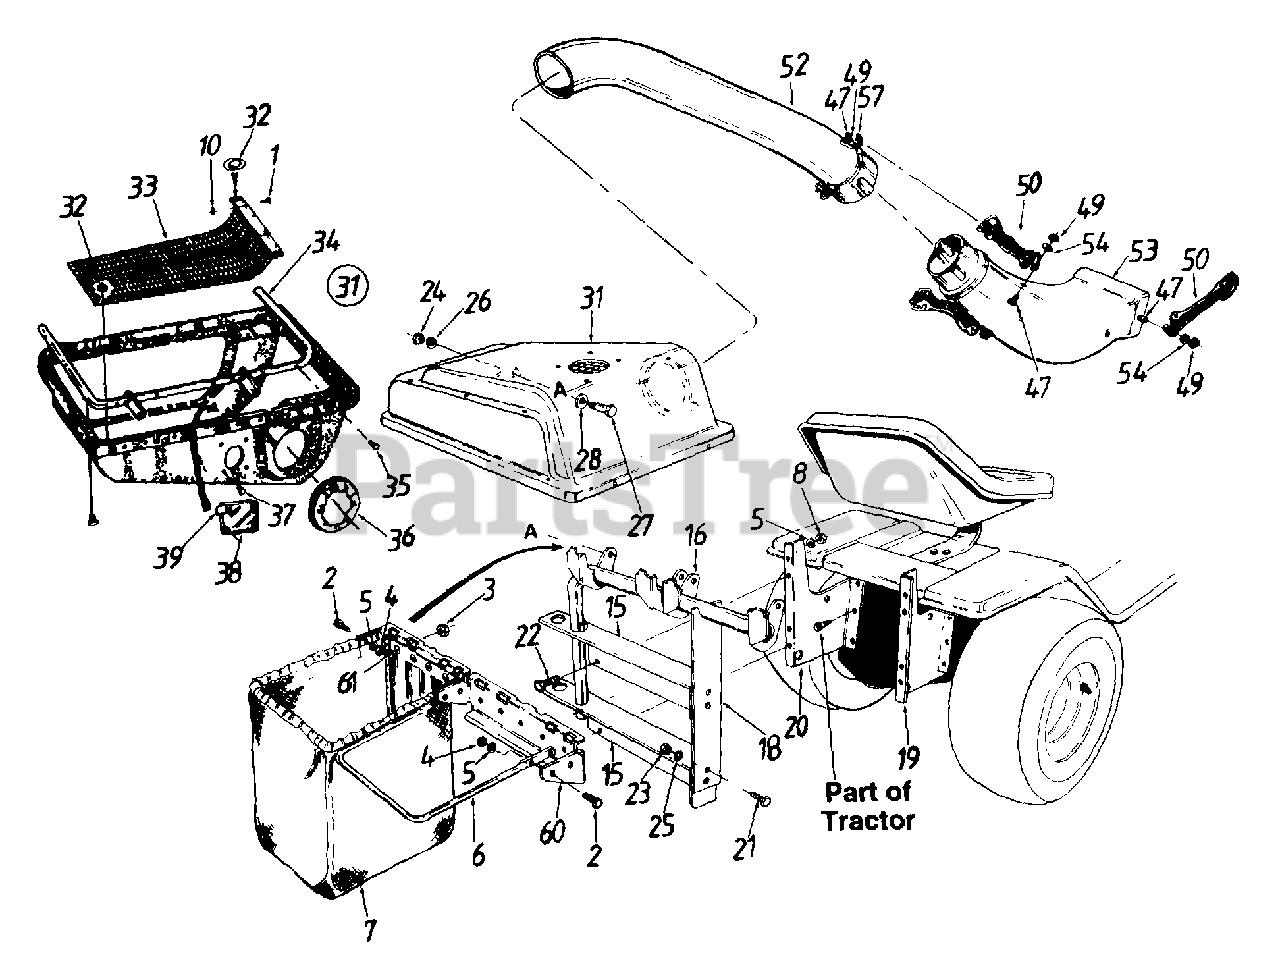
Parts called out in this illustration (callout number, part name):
1	Pop Rivet .188 Dia.
2	Hex Bolt 1/4-28 x .88"
3	Hex Sems Nut #10-24 Thd.
4	Hex Nut 1/4-28 Thd.
5	L-Wash, 1/4" I.D.
7	Grass Catcher Bag
8	Hex Nut 1/4-20 Thd.
10	Flat Wash. 1/4" I.D.
15	Catcher Support Tube Mtg. Brkt.
22	Hex Bolt 1/4-20 x .62" Lg.- Grade 5
23	Hex Nut 5/16-18 Thd.
24	Hex Nut 3/8-16 Thd.
25	L-Wash. 5/16" I.D.
26	L-Wash. 3/8" I.D.
27	Shld. Bolt 3/8-16 x .50" Dia.
28	Bell-Wash..505" I.D. x 1.0" O.D.
31	Grass Catcher Cover Ass'y.
32	Twist Fastener
35	Hex AB-Tap Scr 1/4 x 62"
36	Seal - 7"
37	Truss 8-Tap Scr. #10 x .5" Lg.
38	Plastic Plate
39	Speed Nut
47	Hex Bolt 1/4-20 x .625"
49	Hex Ins. L-Nut 1/4-20 Thd.
50	Retainer Strap Ass'y.
52	Catcher Tube
53	Discharge Chute
54	L-Wash..27" I.D.
57	Retainer Hook Brkt.
61	Truss Mach. Scr. #10-24 x .5"
